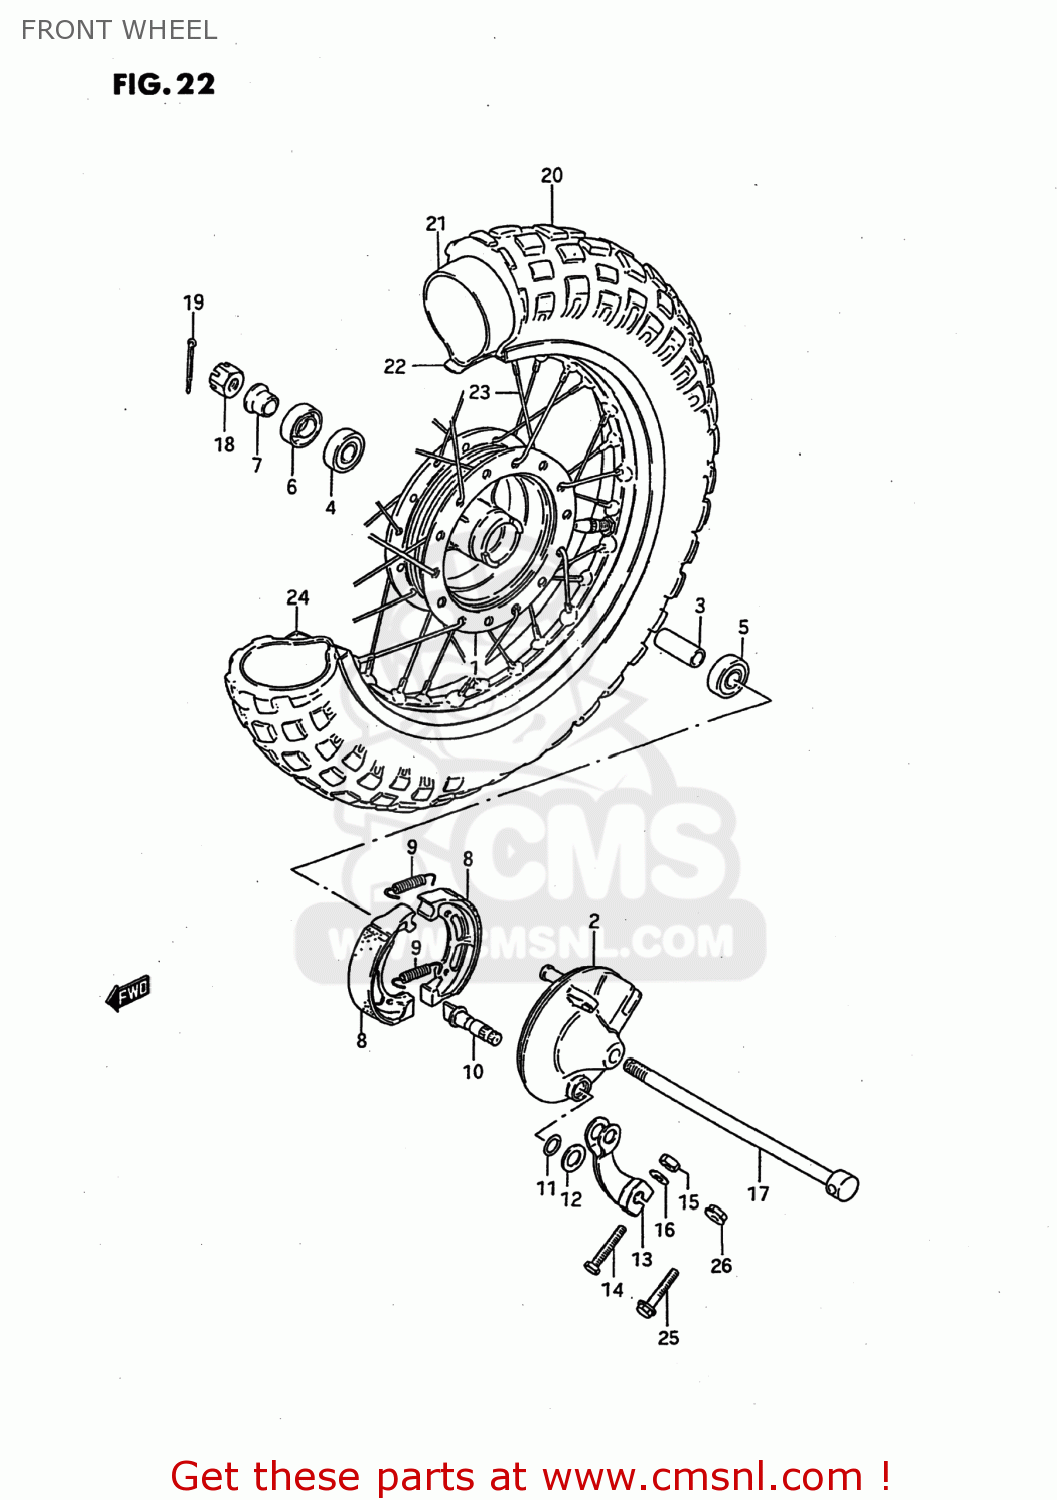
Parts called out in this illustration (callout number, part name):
1	HUB,FR WHEEL
2	PANEL,FR BRAKE ANCHOR
3	SPACER(10.2X16X47)
4	BALL BEARING K
5	BEARING
6	SEAL,OIL(15X27X6)
7	SPACER,AXLE
8	SHOE,BRAKE
9	SPRING(L:35.8)
10	CAM,BRAKE
11	O RING(D:2.4,ID:9.8)
12	WASHER (10.5X18X1)
13	LEVER,FR BRAKE CAM
14	BOLT
15	NUT 5MM
16	WASHER
17	AXLE,RR
18	NUT
19	PIN 20X20
20	TIRE
21	TUBE,INNER
22	PROTECTOR,INNER TUBE
23	SPOKE SET,RR
24	RIM,WHEEL
25	BOLT
26	NUT
